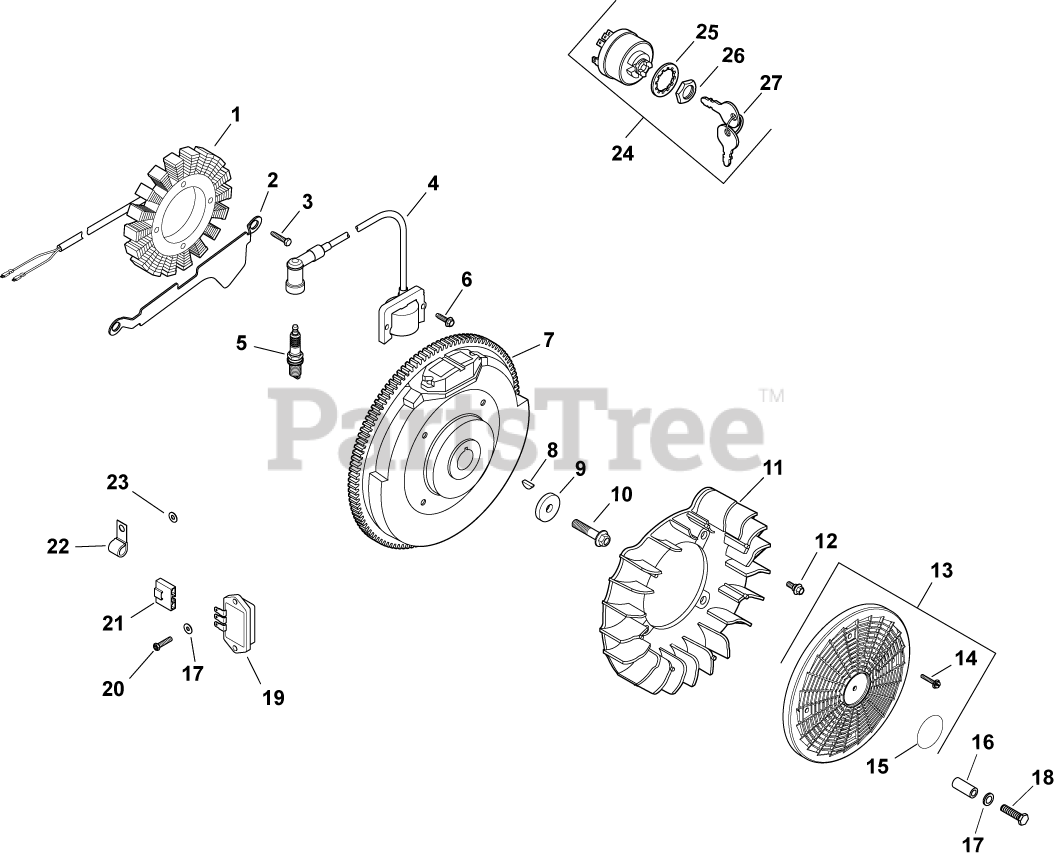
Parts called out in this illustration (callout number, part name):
1	KIT, 15 / 20 AMP STATOR
2	BRACKET, STATOR WIRE
3	SCREW, M5X0.8X25 - (#25086402S)
5	PLUG, SPARK (STD)
6	SCREW, SKT THD FRM M5X0.8X25
7	FLYWHEEL, PAINTED-USE 24 025 57-S
8	KEY, 3/16" X 5/8"
9	WASHER, FLAT 13/32"
10	SCREW, FLG M10X1.5X45 - (#25086361S)
11	FAN (WITH HOLE)-USE 24 157 16-S
12	BOLT, SHOULDER
13	KIT, GRASS SCREEN
14	SCREW, WSH HD TAP #8-18X1/2"
15	DECAL, GRASS SCREEN USE 24 113 499-S
16	SPACER - DISCONTINUED
17	WASHER, FLAT 3/16"
18	SCREW, SLT HD CAP M4X0.7X25
19	REG/RECT-15 AMP (KM)-USE 41 403 10-S
20	SCREW, PHL HD #11-16X7/8"
21	CONNECTOR, BODY (KM)-USE 25 155 41-S
22	CLIP, CABLE
23	WASHER, FLAT 1/4" (O.D. 1/2")
24	SWITCH ASSY, KEY (KM)-USE 25 099 32-S
25	WASHER, INTERNAL TOOTH
26	NUT, KEY SWITCH
27	KEY, SET -USE 48 340 01-S
